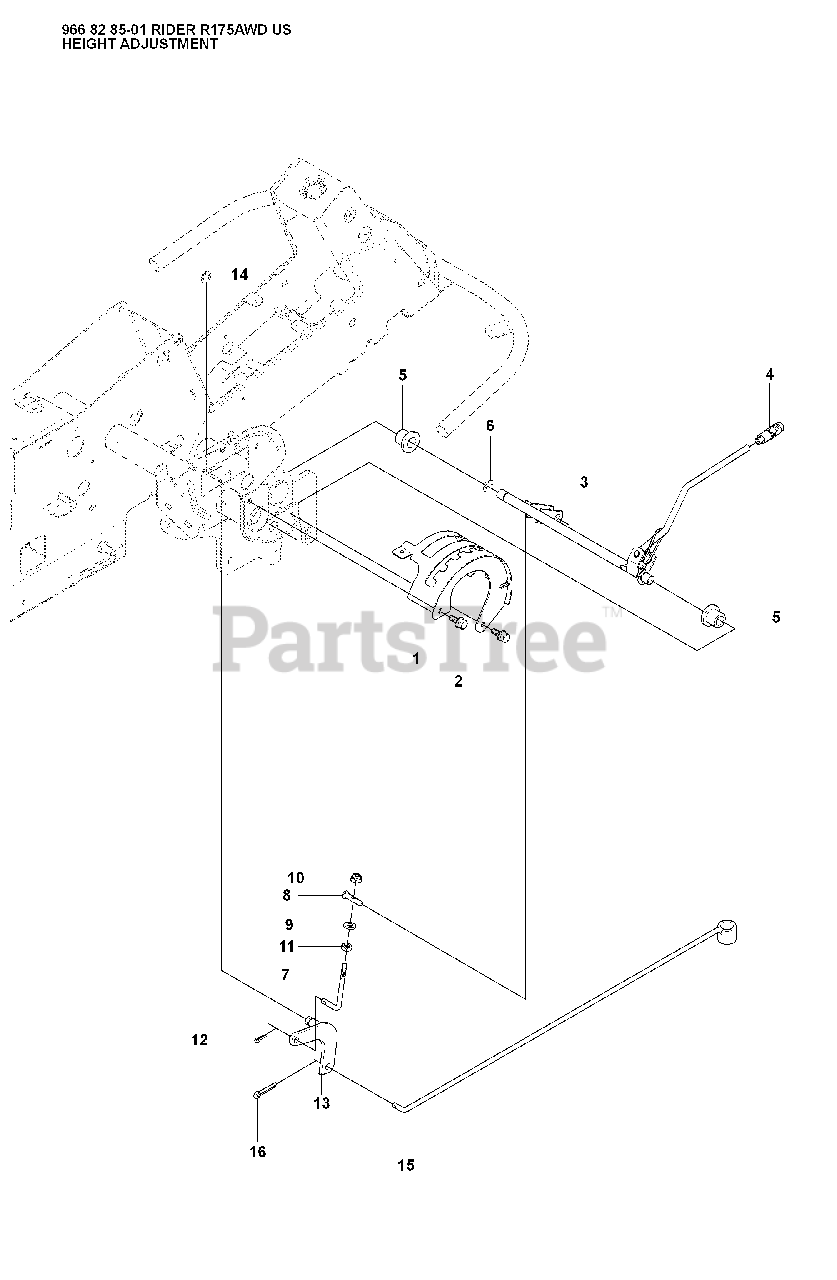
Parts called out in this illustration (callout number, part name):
1	CONTROL PLATE
3	HEIGHT ADJUSTER
4	GEAR STICK KNOB
5	BUSHING
9	WASHER
10	LOCKNUT M8
11	NUT
14	RETAINING RING
15	CLUTCH ROD
